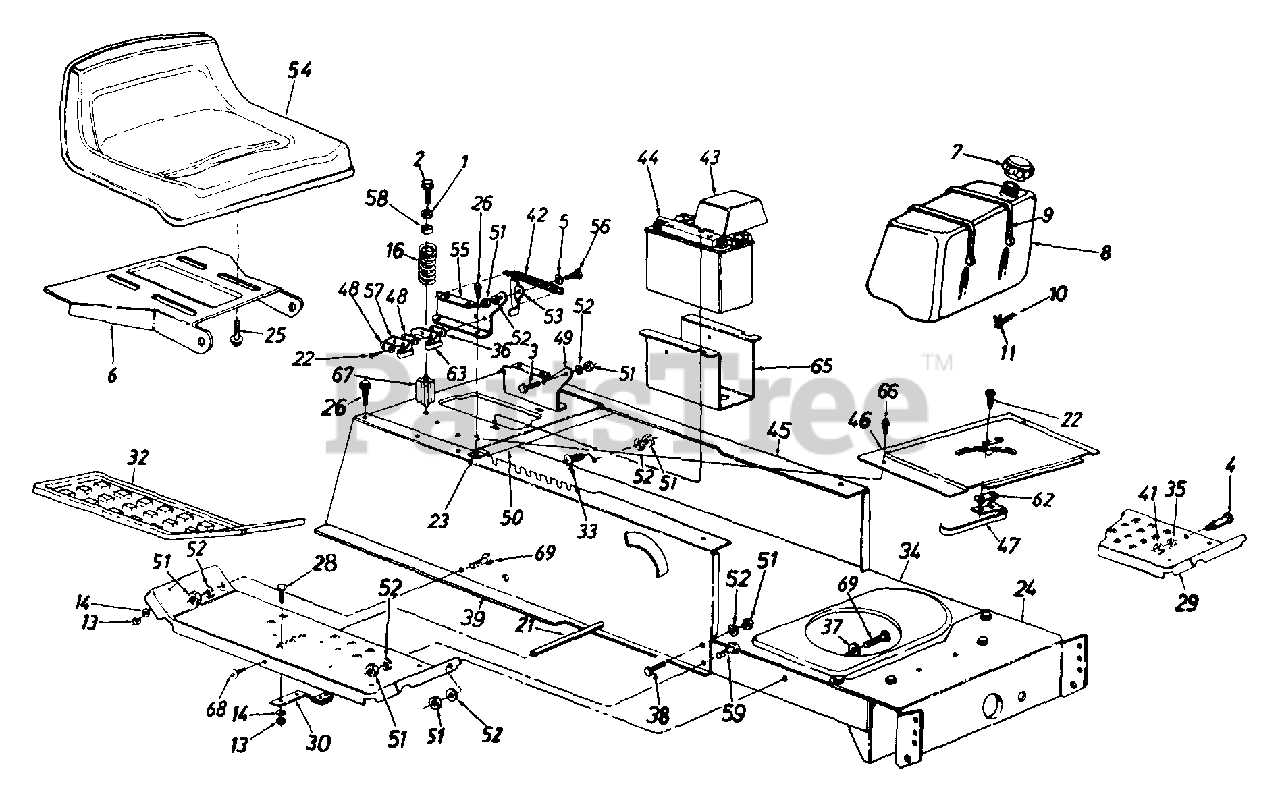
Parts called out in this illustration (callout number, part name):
1	Fl-Wash. .344" I.D. x .875"
2	Hex Wash. Hd. Tap Scr. 5/16-18 x 3.25" Lg.
3	Shld. Bolt .437" Dia. x .162"
4	Shld. Bolt .50" Dia. x .84"
5	Spr-Wash. .445" I.D. x.75
7	Fuel Cap
8	Fuel Tank
9	Tie Strap
10	Fuel Line
11	Hose Clamp
13	Hex Nut 1/4-20 Thd.
14	L-Wash. 1/4" I.D.
16	Compression Spring
21	Running Board Rod
22	Hex Wash. Hd. AB-Tap Scr. #8 x .50" Lg.
23	Speed Nut #10Z
24	Front Pivot Brkt.
25	Hex Tap Scr. 3/8-16 x .75"
26	Hex Wash. Hd. AB-Tap Scr. 5/16 x .75" Lg.
28	Carriage Bolt 1/4-20 x .62"
29	Running Board (R.H. & L.H.)
30	Blade Brake Ass'y.
32	Rubber Foot Pad - L.H.
33	Truss Mach. Scr. 5/16-18 x .75" Lg.
34	Lower Frame
35	L-Wash. 3/8" I.D.
36	Insulator Boss Plate
37	Fl-Wash. .344" I.D. x .625" O.D.
38	Hex Bolt 5/16-18 x .75" Lg.
42	Extension Spring 5.31" Lg.
43	Battery Cover
44	12-V Battery (275 Cold Crank Amps)
45	Upper Frame - L.H.
46	Shift Cover
47	Reverse Safety Switch
48	Insulator Plate
52	L-Wash. 5/16" I.D.
53	Seat Lift Brkt.
54	Seat 8-7/8" High
56	Shld. Bolt .437" Dia. x .268"
57	Spring Switch
58	Bushing
59	Hex Wash. TT -Tap Scr. 5/16-18 x 7/8" Lg.
62	Insulator Nut Plate
63	Safety Switch (Seat)
65	Battery Tray
66	Truss Mach. B-Tap Scr. #10 x .5" Lg.
67	Spring Spacer
68	Pan Hd. Cutting Scr. 5/16-18 x .75" Lg.
69	Hex Bolt 5/16-18 x .75" Lg.
17622C-0637	FRAME-UPPER RH SID - POWDER BLACK (0637)
17622C-0638	FRAME-UPPER RH SID - MTD/TROY-BILT RED (0638)
